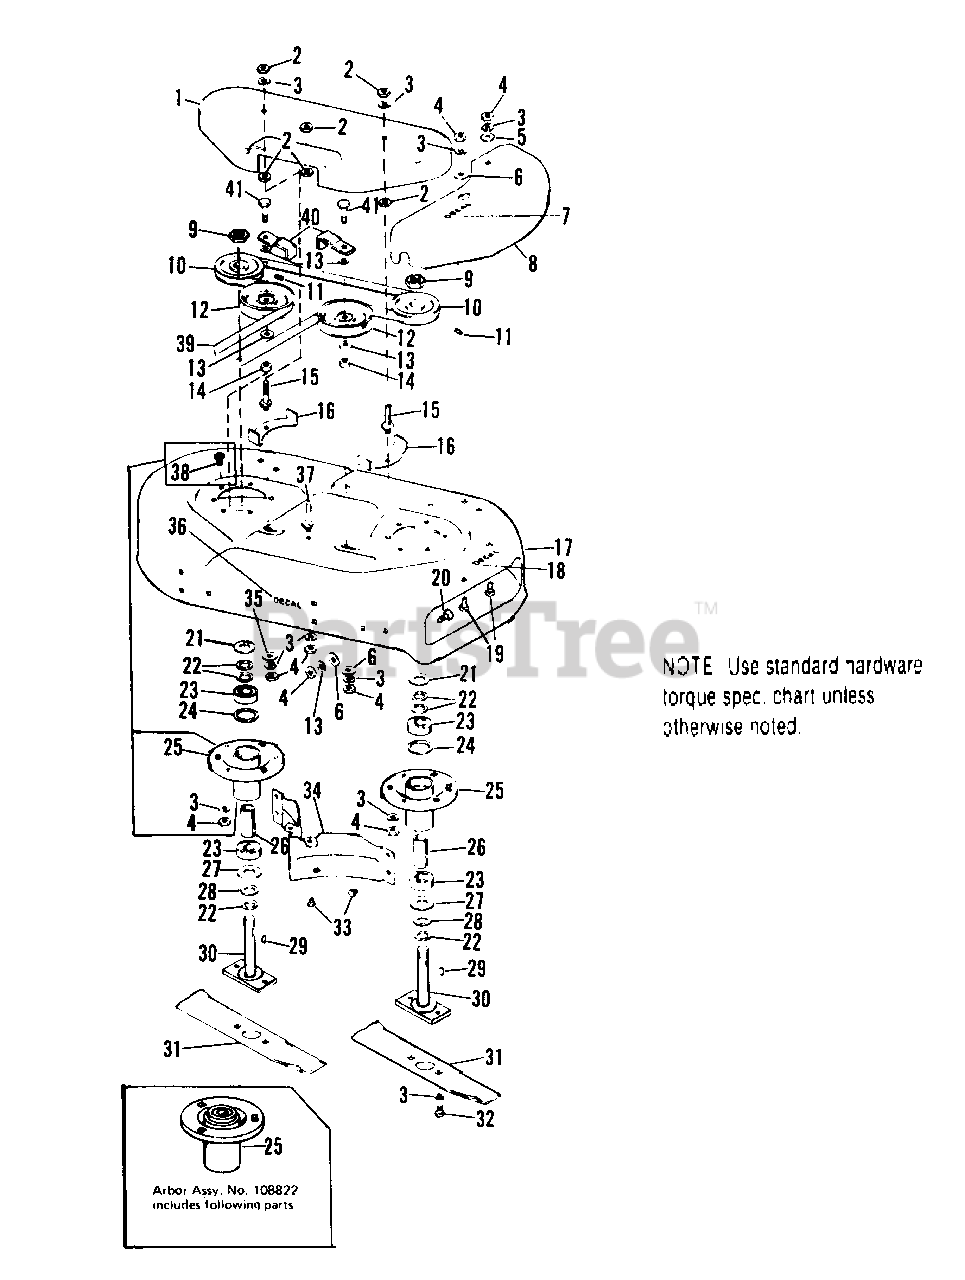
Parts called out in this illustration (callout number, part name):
1	COVER, Housing
2	LOCKNUT, Hex, 3/8-16
3	LOCKWASHER, 3/8
4	NUT, Hex, Full, 3/8-16
5	WASHER, Plain, 5/16
6	WASHER, Special
7	DECAL, Safety
8	DEFLECTOR
9	LOCKNUT, Hex, Jam, 3/4-16
11	SETSCREW, 5/16-18 x 3/8
12	PULLEY, Idler
13	WASHER, Plain, 3/8
16	GUIDE, Belt
17	HOUSING, Mower
18	DECAL, Safety
19	BOLT, Carriage, 5/16-18 x 3/4
20	BOLT, Carriage, 3/8-16 x 3/4
24	RING, Backing
25	TUBE ASSY., Arbor
29	KEY, Woodruff, #61
30	ARBOR ASSY.
32	CAPSCREW, Hex Hd., 3/8-16 x 5/8
33	SCREW, Hex, Taptite, 1/4-20 x 3/8
35	WASHER, Plain, 5/16
36	DECAL, Simplicity
38	CAPSCREW, Hex Hd., 3/8-16 x 3/4
40	GUIDE, Belt
41	CAPSCREW, Hex Hd., 3/8-16 x 1-3/4
